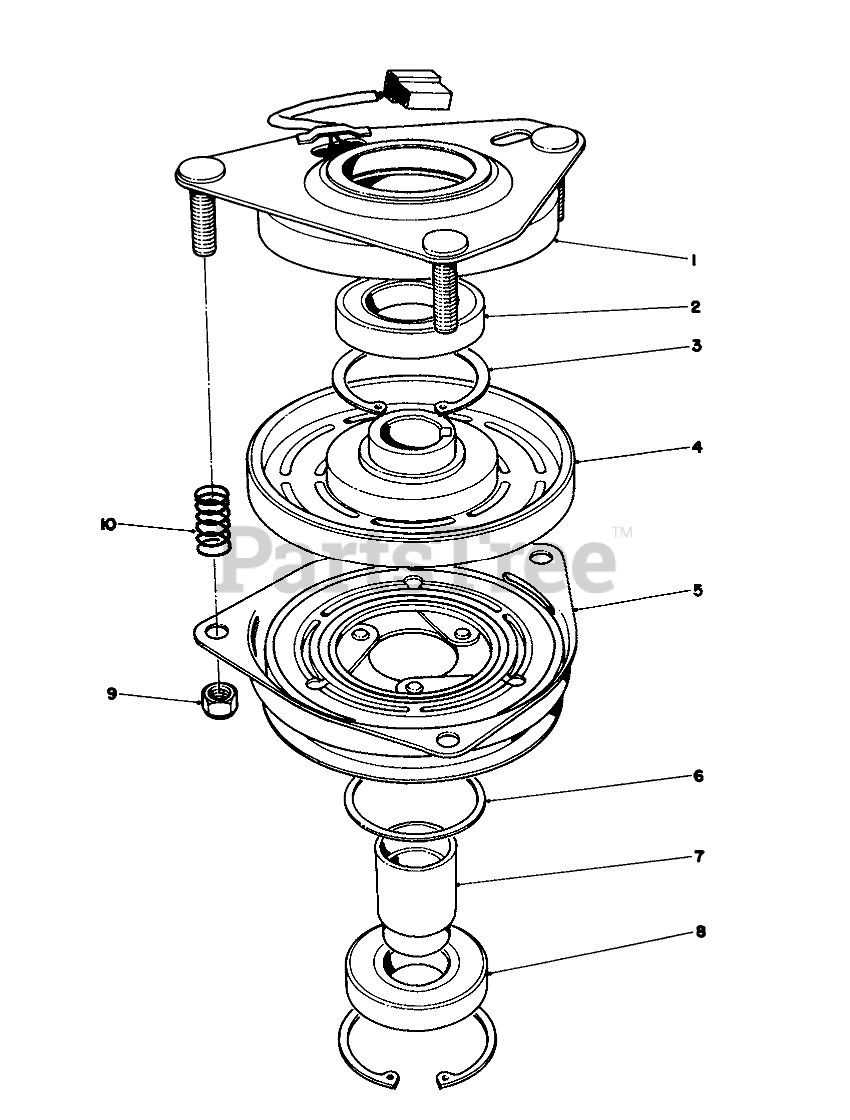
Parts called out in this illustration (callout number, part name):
1	Field Assembly (Incl. Ref. #2 & 3)
2	BEARING-FIELD
3	RING-RETAINING
4	Field Coil, Rotor & Bearing Assembly (Incl. Ref. #1)
5	Armature & Pulley Assembly (Incl. Ref. #3, 6, 7 & 8)
6	SPACER-BEARING, PULLEY
7	COLLAR-BEARING
8	BEARING-PULLEY
9	NUT-LOCK
10	SPRING
